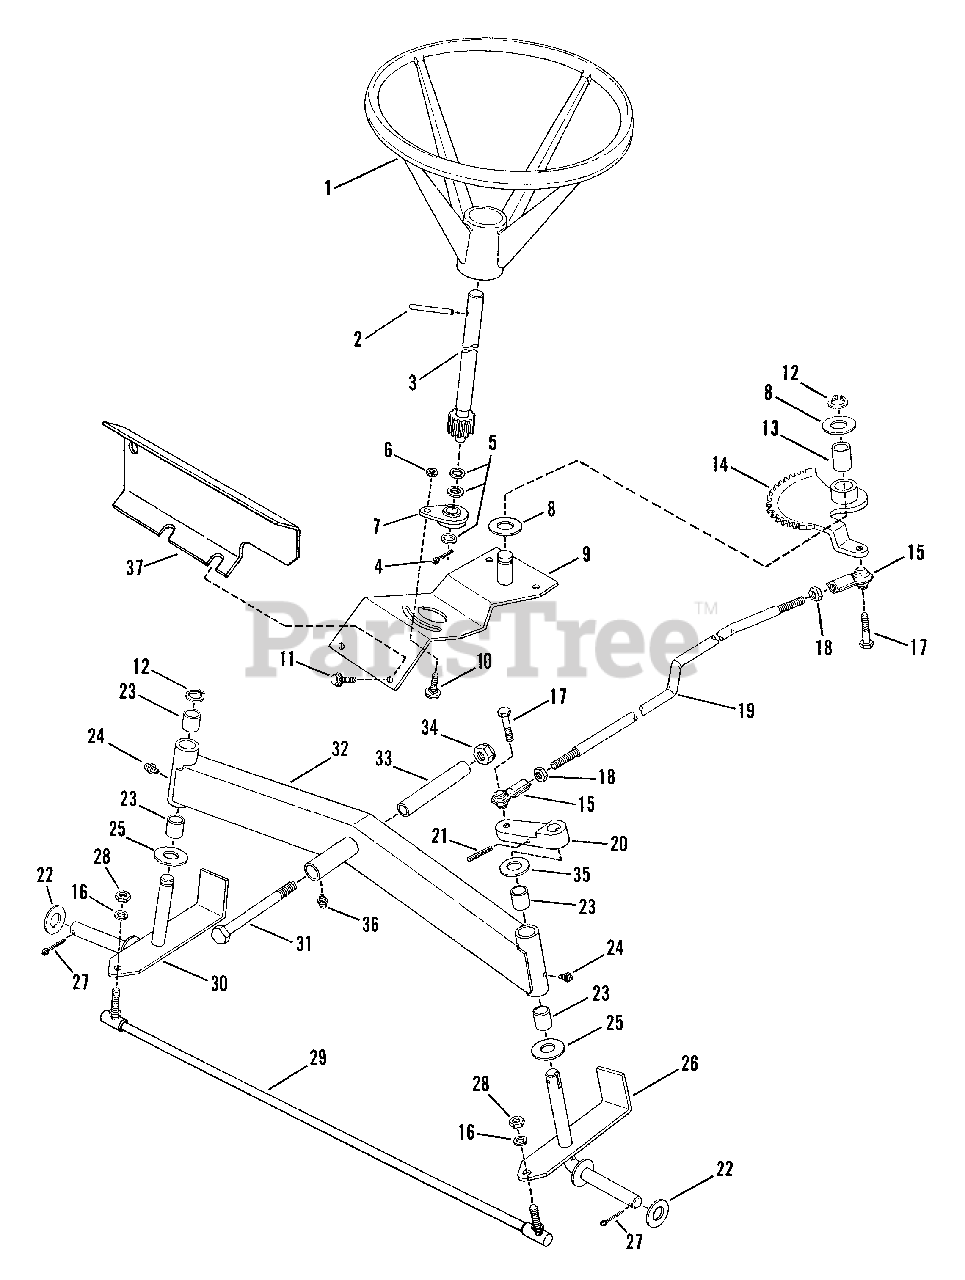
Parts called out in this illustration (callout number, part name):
1	STEERING WHEEL
2	ROLL-PIN Spiral .26 x 2.25
3	SHAFT, Steering
4	PIN, Cotter 3/32 x 1.0 YZ
5	WASHER, Shim .5 x .75 x .03
6	NUT, 1/4-20 hex Flange Lock
7	ADJUSTER, Steering
8	WASHER, Thrust
9	ASSEMBLY, Steering Support
10	BOLT, 1/4-20 x 5/8" Short Neck Carriage
11	SCREW, 5/16-18 x 5/8" Self-Tapping
12	RING, Retaining EXT .625
13	BEARING
14	ASSEMBLY, Sector
15	BALL JOINT, Drag Link .377 ID Ball x 3/8-24 End
16	WASHER, 3/8 Split Lock
17	SCREW, 3/8-24 x 1 1/4" Hex Head Cap Nylon Patch
18	JAM-NUT, 3/8-24 Hex
19	DRAG-LINK
20	ARM, Steering
21	ROLL-PIN 1/4 x 1.25"
22	WASHER, Flat .77 x 1.5 x .06
23	BEARING, Sleeve .875 OD
24	LUBE FITTING, Straight (press-fit for .187 dia. Hole)
25	WASHER, Thrust
26	SPINDLE ASSEMBLY, L.H.
27	COTTER-PIN 5/32 x 1 YZ
28	NUT, 3/8-24 Hex
29	TIE-ROD
30	SPINDLE ASSEMBLY, R.H.
31	SCREW, 1/2-20 x 4 1/2" Hex Head Cap
32	ASSEMBLY, Front Axle
33	SPACER, Axle Pivot .748 OD x .508 ID x 3.77 L
34	NUT, 1/2-20 Hex Lock
35	WASHER .77 x 1.13 x .06
36	FITTING, Lube 3/16
37	HEAT SHIELD, Fuel Line
